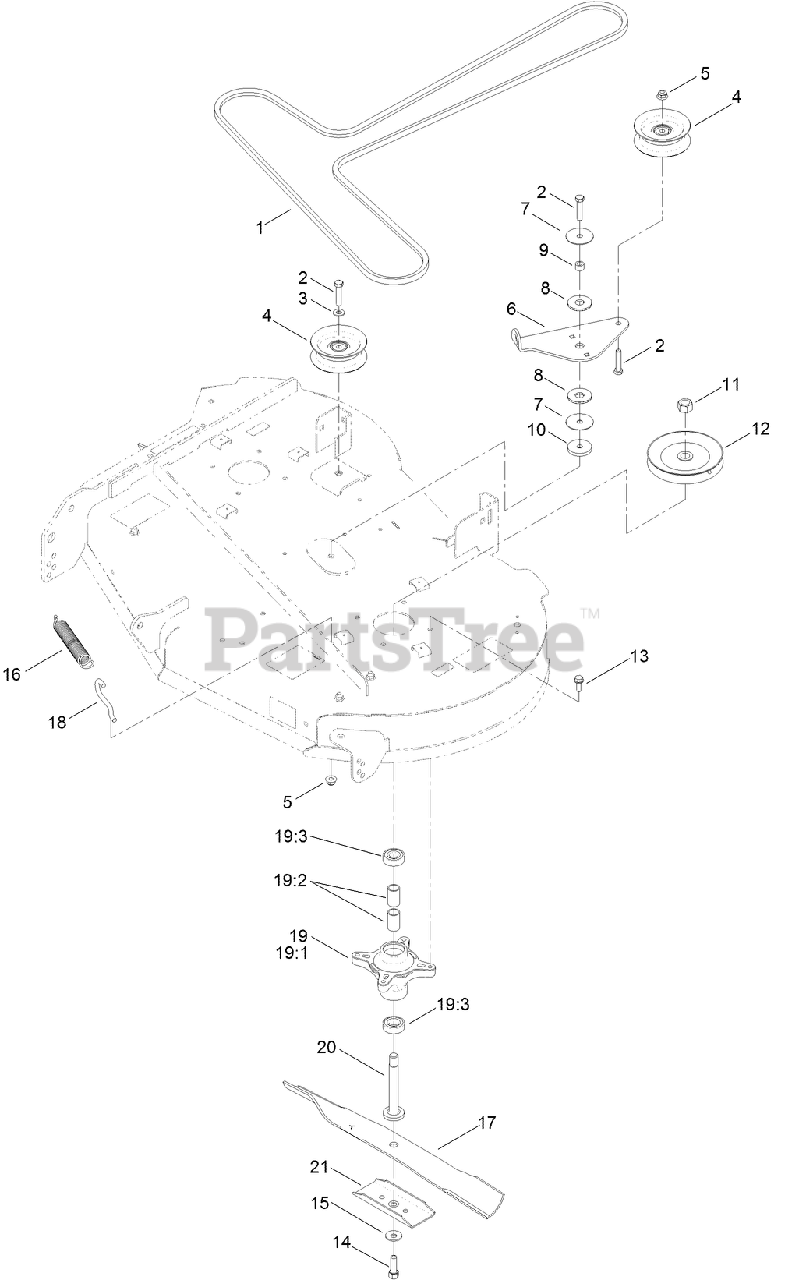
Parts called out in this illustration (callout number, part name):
1	V-BELT
2	SCREW-HH
3	WASHER-FLAT
5	NUT-HF, NI
6	ARM-IDLER
7	WASHER
8	WASHER-FRICTION, COMPOSITE
9	SPACER
10	WASHER-PLAIN
11	NUT-HEX
12	PULLEY
13	SCREW-TAPTITE
14	SCREW-HH
15	WASHER-BELLEVILLE
16	SPRING-EXTENSION
18	HOOK-RETURN, SPRING
19	SPINDLE ASM
19:2	SPACER
20	SHAFT-SPINDLE
21	STIFFENER-BLADE
